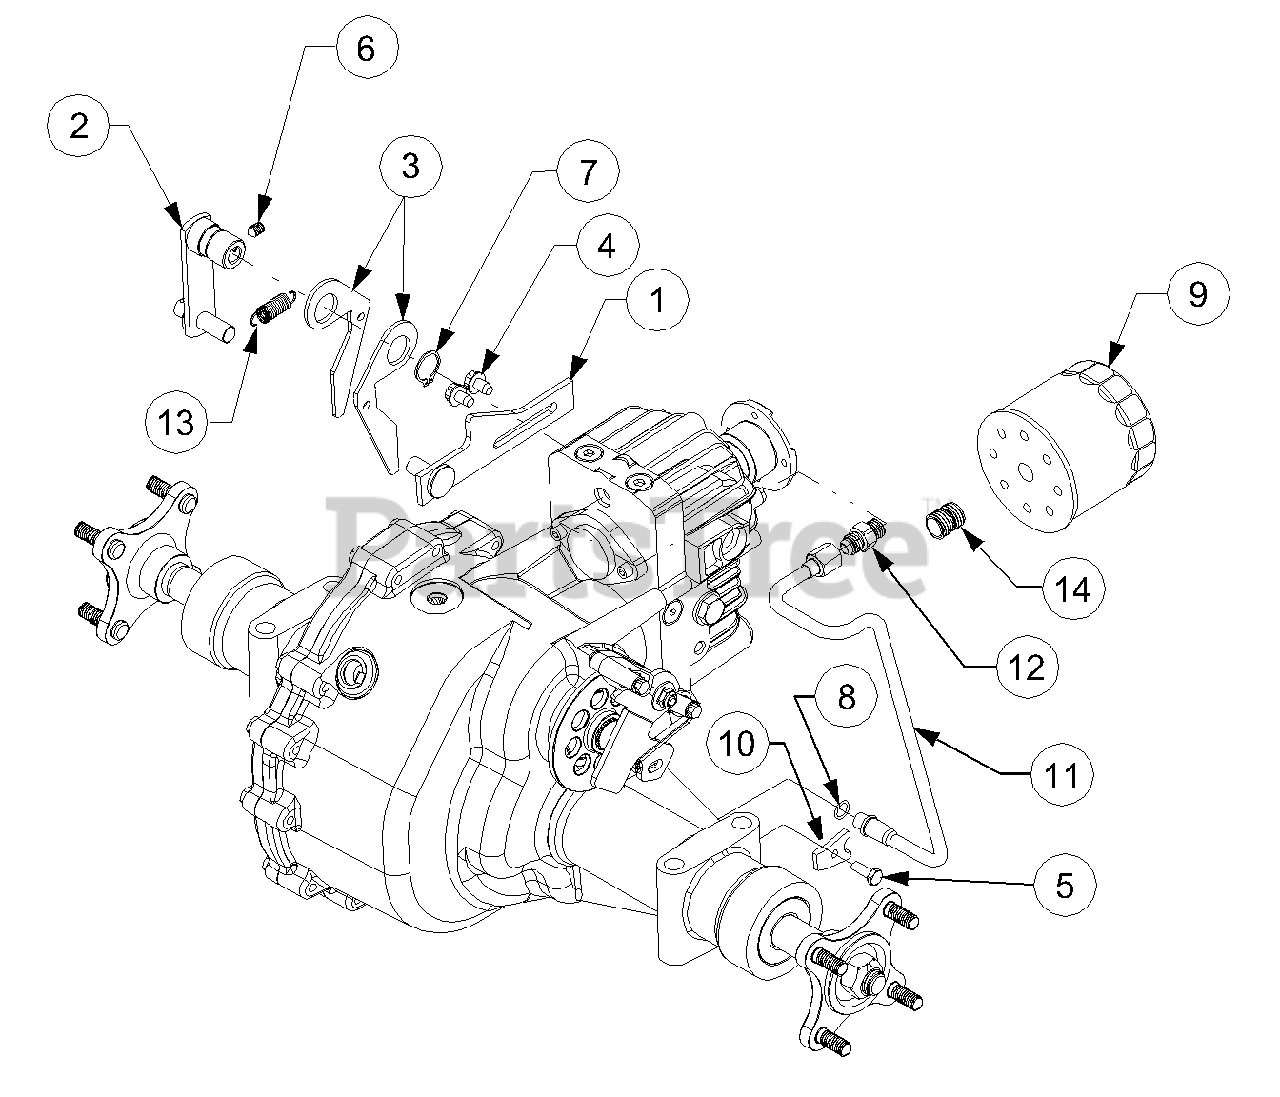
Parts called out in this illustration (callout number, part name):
1	Bracket, Neutral Return
2	Arm Assembly, Control
3	Arm, Neutral
4	Screw, Hex Wash Hd Tapp, 5/16-18 x .50
5	Screw, Hex Cap, 1/4-20 x .75 GR5
6	Screw, Set w/Lock Patch, 5/16 x .50
7	Ring, Snap, .875 Shaft
8	O-Ring, .426 ID x .566 OD x .07
9	Filter, Oil
10	Clamp, Tube, .50
11	Tube, Hydro Pickup
12	Fitting, Hydraulic Straight
13	Spring, Extension .477 OD x 1.68 Lg
14	Nipple, Oil Filter
